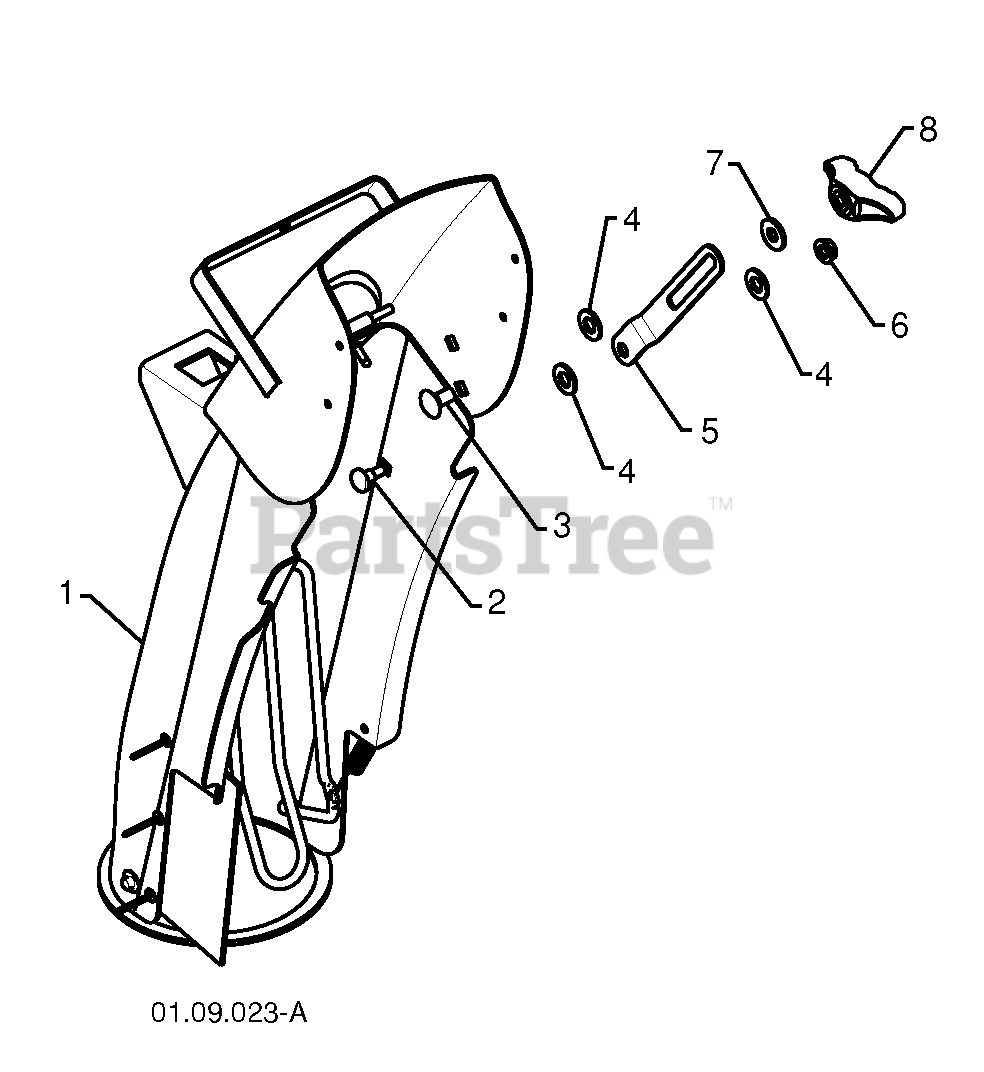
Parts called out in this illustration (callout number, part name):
2	SHOULDER BOLT
3	BOLT
4	WASHER, NYLON FRICTION
5	RP STRAP, SLOTTED
6	NUT.HEX.FLANGE.1/4
7	WASHER.20X8.5
8	KNOB, DEFLECTOR
